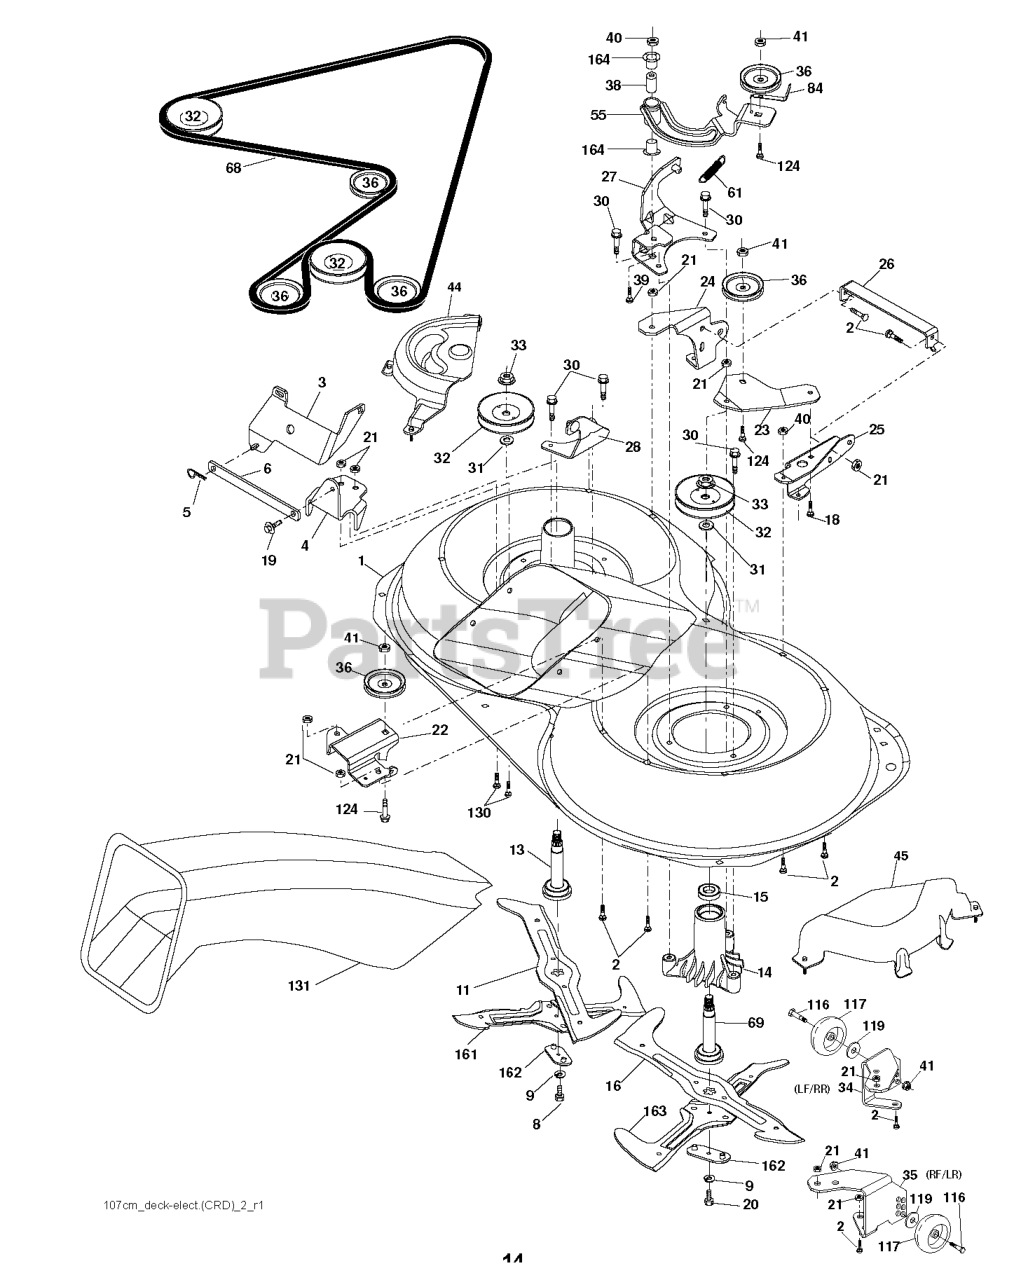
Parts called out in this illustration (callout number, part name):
1	Housing Asm. Mower 107 CRD
2	RP BOLT 5/16-18 X3/4 ZN/YEL GR
3	BRACKET.ASM.BAR.SWAY.CHASS
5	RETAINER-SPRNG RB
6	BAR.SWAY.92.CRD
8	BOLT.3/8-24X1.25 GR8
9	LOCKWASHER
11	BLADE.3N1.LH.CRD
13	SHAFT ASM VENT
14	HOUSING.MANDREL.VENTED (MACHD)
16	BLADE.3N1.RH.CRD
19	BOLT SHD 5/16-18
20	BOLT.3/8-24X1.25GR8. LHTHRD
21	LOCKNUT
22	BRACKET.IDLER.RR.107.CRD
24	BRACKET
25	BRACKET RF
26	SUPPORT
28	BRACKET
30	SCREW, WASHER HEAD
31	WASHER.SPACER.MANDREL
32	PULLEY.MANDREL.4.80 PD.2006
33	NUT.FLANGE.LOCK.TOP
34	BRACKET
35	BRACKET
36	PULLEY.IDLER.4.25
41	NUT LOCK FLG 3/8-16 UNC
45	COVER.MANDREL.RH.CRD
46	SCREW.1/4-20X5/8
55	ARM.IDLER.107.CRD
61	SPRING
68	HEX-BELT 107 MOWER
69	SHAFT.ASM.W/LWR.BRG.RH.THREAD
84	KEEPER, BELT IDLER
116	BOLT.SHOULDER.3/8-16X3-5/8.
117	RP WHEEL. GUAGE RALLY
119	WASHER
124	BOLT.3/8-16X1.50
130	BOLT.CARR.SQNK.5/16-18UNC.X3/4
131	CHUTE BAGGER
163	BLADE.CROSS.RH.CRD.107
164	BRNG T
